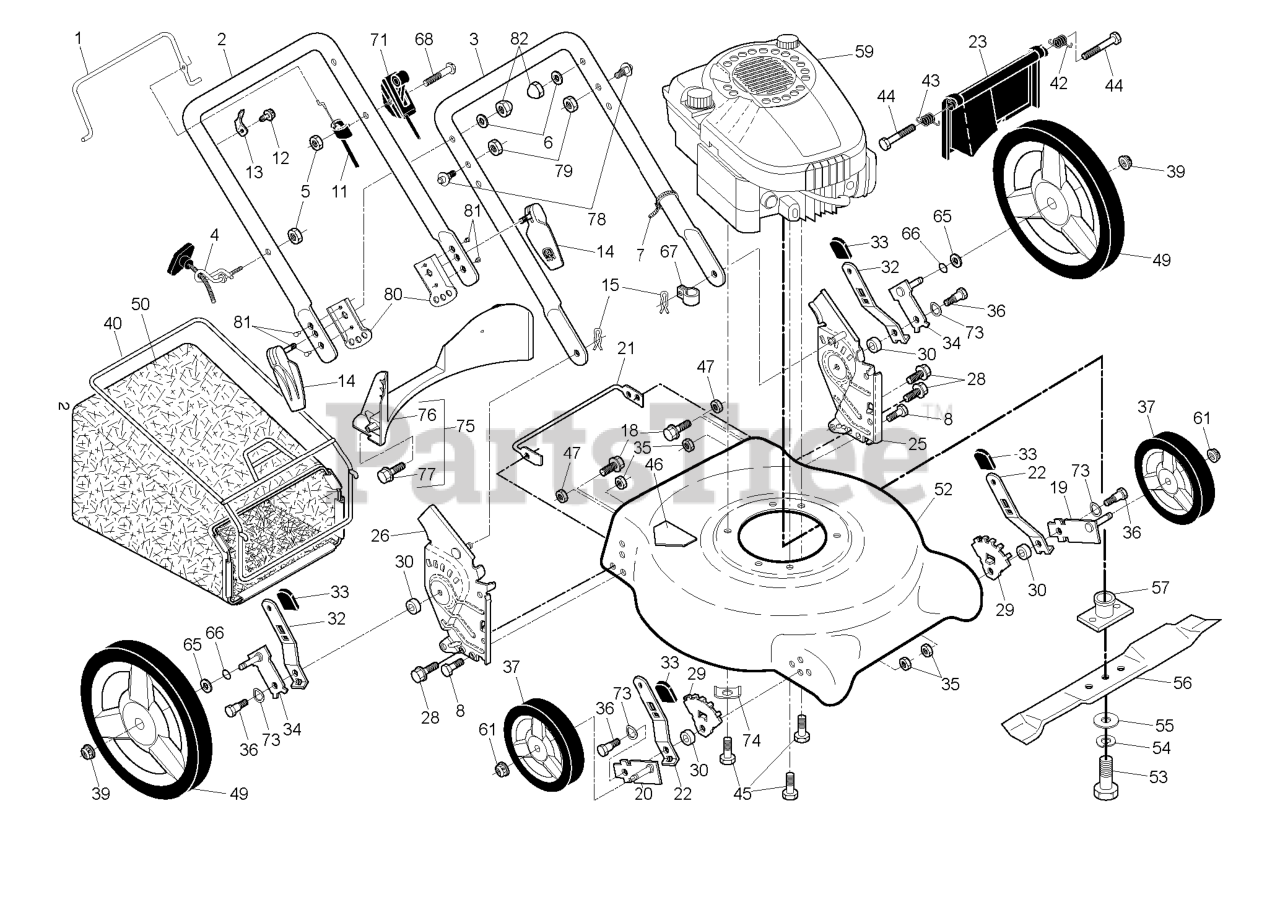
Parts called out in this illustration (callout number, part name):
1	BAIL.MZR.STD.ORANGE
3	HANDLE.LOWER.ECON.PNT
4	RB GUIDE.ROPE.STD.BLK.ZIN WSL
5	NUT
6	Locknut, Hex 1/4-20
7	TIE GUIDE
8	BOLT.FIN.HEX.5/16-18X3/4
11	CABLE.MZR.B&S.45.LT.PUSH
13	BRACKET.UPSTOP.RT
14	QUICK.ASM.RELEASE.BLACK
15	HAIRPIN COTTER
18	SCREW 1/4X20
19	AXLE ARM ASSY FRONT LH
20	AXLE ARM ASSY FRONT RH
22	SELECTOR SPRING, FRONT
23	REAR DOOR ASSY
25	RP BRKT.ASM.HAND.HW.21.LT.ORNG
26	RP BRKT.ASM.HAND.HW.21RT.ORNG
28	SCREW 14-20 X 5/8
29	FOOT.GUARD.21.DOM/FGD.CE.10
30	SPACER.HEIGHT.ADJUSTER
32	SPRING.SEL.EXT.21.DOMED.12/14
34	AXLE ARM ASSY REAR LH
35	NUT.FLANGE.HEX.5/16X18.BLACK
36	SHOULDER BOLT 5/16-18
37	WHEEL AND TIRE ASSY, REAR
39	NUT.HEX.FLANGE.3/8-16.LOCKNUT
40	FRAME.BAG.21.REAR.DOMED.PUSH
42	SPRING.LH.22.REAR.DOOR.EZ.EMPT
43	SPRING.RH.22.REAR.DOOR.EZ.
45	BOLT 3/8-16X1-1/8
46	DECAL.INTERNATIONL.CUTFINGER
48	AXLE ARM ASSY REAR RH
49	RP.WHEEL.12X1.75H 3 SPOKE.RAD
52	KIT.HSG.21.PUSH.ORANGE.CE
53	SCREW, HEX HD 3/8-24 X 1-3/8
54	LOCKWASHER
55	WASHER,HARDEN
56	BLADE.21.PUSH
57	ADAPTER.BLADE.W/KEY.25MM.CE
61	NUT.HEX.FLANGE.3/8-16.LO(3 2)
65	WASHER.FLAT.1/2
66	O-RING..070X.487.NEOPRENE
67	CLIP.CABLE.BLK
73	WASHER.CURVED.CYLINDRICAL
74	WASHER.ENGINE.BZP
75	KIT.BAFFLE.REAR.PLASTIC.21.RD
76	BAFFLE.REAR.PLASTIC.21.RD.ECON
77	SCREW.HX.13X.750
78	STUD.QUICK.ADJUST
79	NUT.LOCK.5/16-18
80	BRACKET.ADJ.3POS.GREY
82	WASHER.20X8.5
